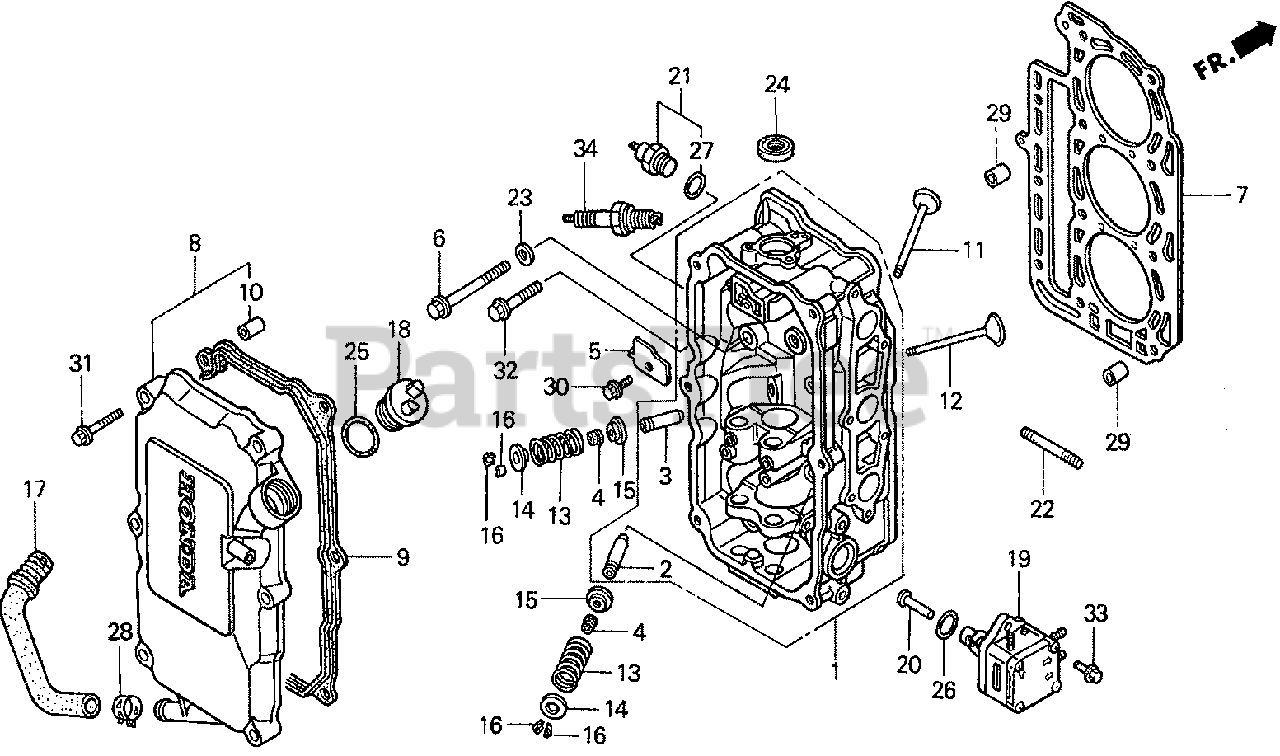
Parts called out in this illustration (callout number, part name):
1	CYLINDER HEAD ASSY. *NH8* (DARK GRAY) (NOT AVAILABLE)
1	CYLINDER HEAD *NH8* (DARK GRAY)
2	GUIDE, VALVE (OS)
3	GUIDE, EX. VALVE (OS)
4	SEAL, VALVE STEM
5	PLATE, OIL CHAMBER
6	BOLT, FLANGE (8X80)
7	GASKET, CYLINDER HEAD
8	COVER, CYLINDER HEAD
9	GASKET, HEAD COVER
10	COLLAR, HEAD COVER
11	VALVE, IN.
12	VALVE, EX.
13	SPRING, VALVE
14	RETAINER, VALVE SPRING
15	SEAT, VALVE SPRING
16	COTTER, VALVE (SANKO)
17	TUBE, OIL
19	PUMP ASSY., FUEL
20	LIFTER, FUEL PUMP
21	SWITCH ASSY., THERMOSTAT
22	BOLT, STUD (6X28)
23	WASHER, PLAIN (8MM)
24	OIL SEAL (20X32X6)
25	O-RING (26X2.7)
26	O-RING (20.8X2.4)
27	O-RING (13.5X1.4)
28	CLAMP, TUBE (D17)
29	PIN, DOWEL (10X12)
30	BOLT, FLANGE (6X12)
31	BOLT, FLANGE (6X35)
32	BOLT, FLANGE (8X40)
33	BOLT, FLANGE (6X20)
34	SPARK PLUG (DR7EA) (NGK)
34	SPARK PLUG (X22ESR-U) (DENSO)
